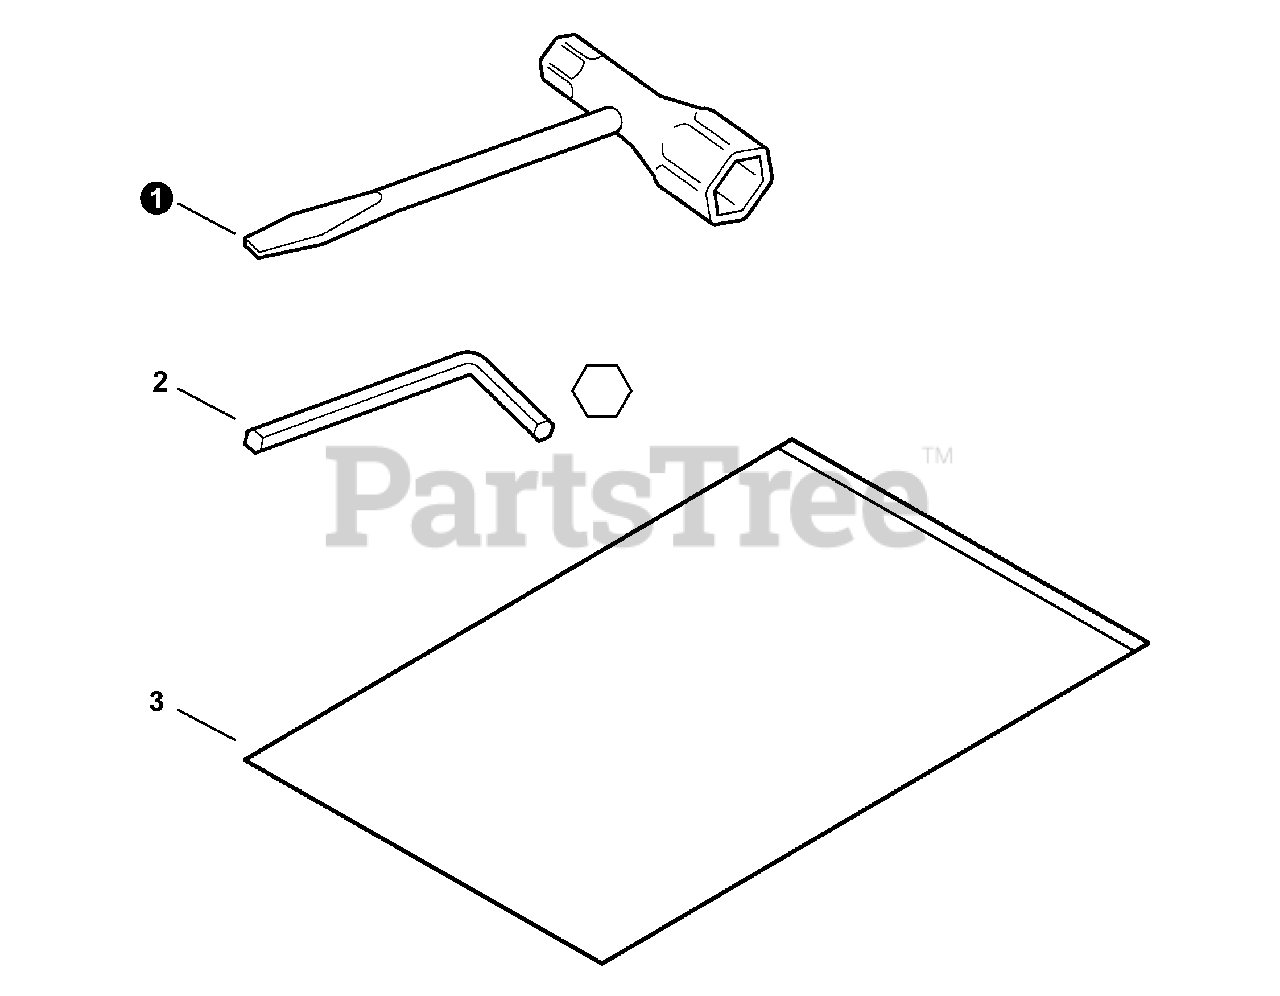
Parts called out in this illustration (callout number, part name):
1	T-WRENCH 16×13
2	WRENCH, ALLEN 4 MM
3	BAG, TOOL
